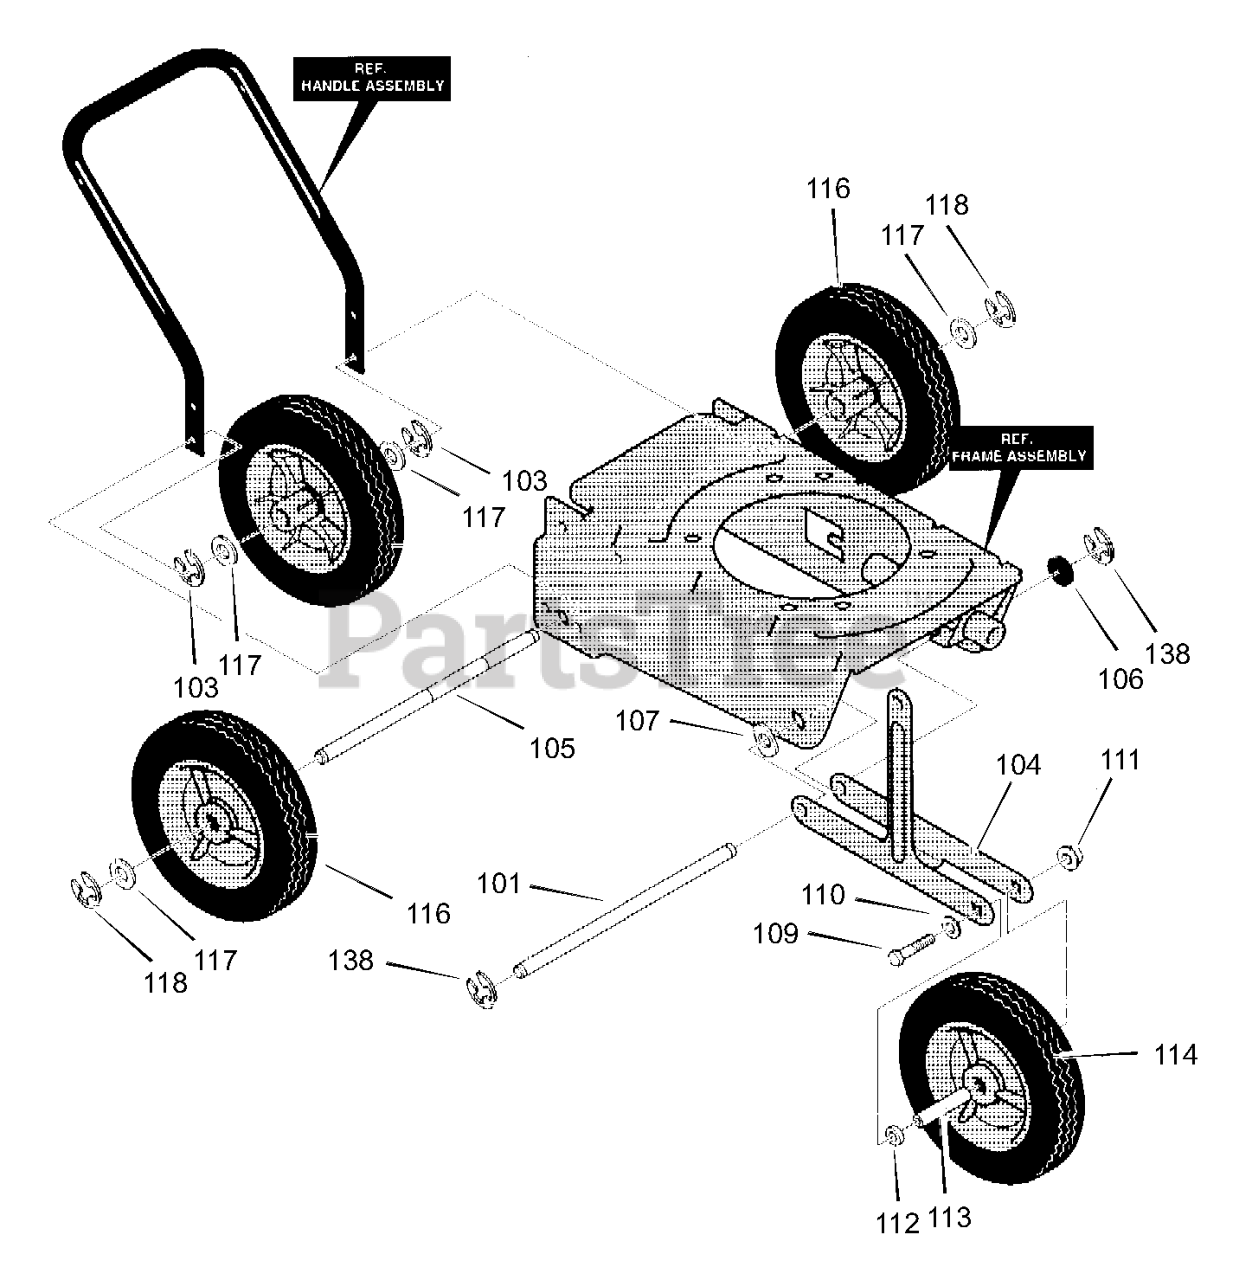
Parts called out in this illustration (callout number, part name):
101	Rod, Axle Front
103	E-Ring
104	Bracket, Curp Hop
105	Rod, Rear Axle
106	Washer, Flat
107	Washer, Spring
108	Tire & Rim
110	Washer, Flat
111	Nut, 5/16-18
112	Washer, Nylon
113	Spacer, Sleeve
114	Tire & Rim
116	Tire & Rim
117	Washer, Flat
118	E-Ring
138	E-Ring
